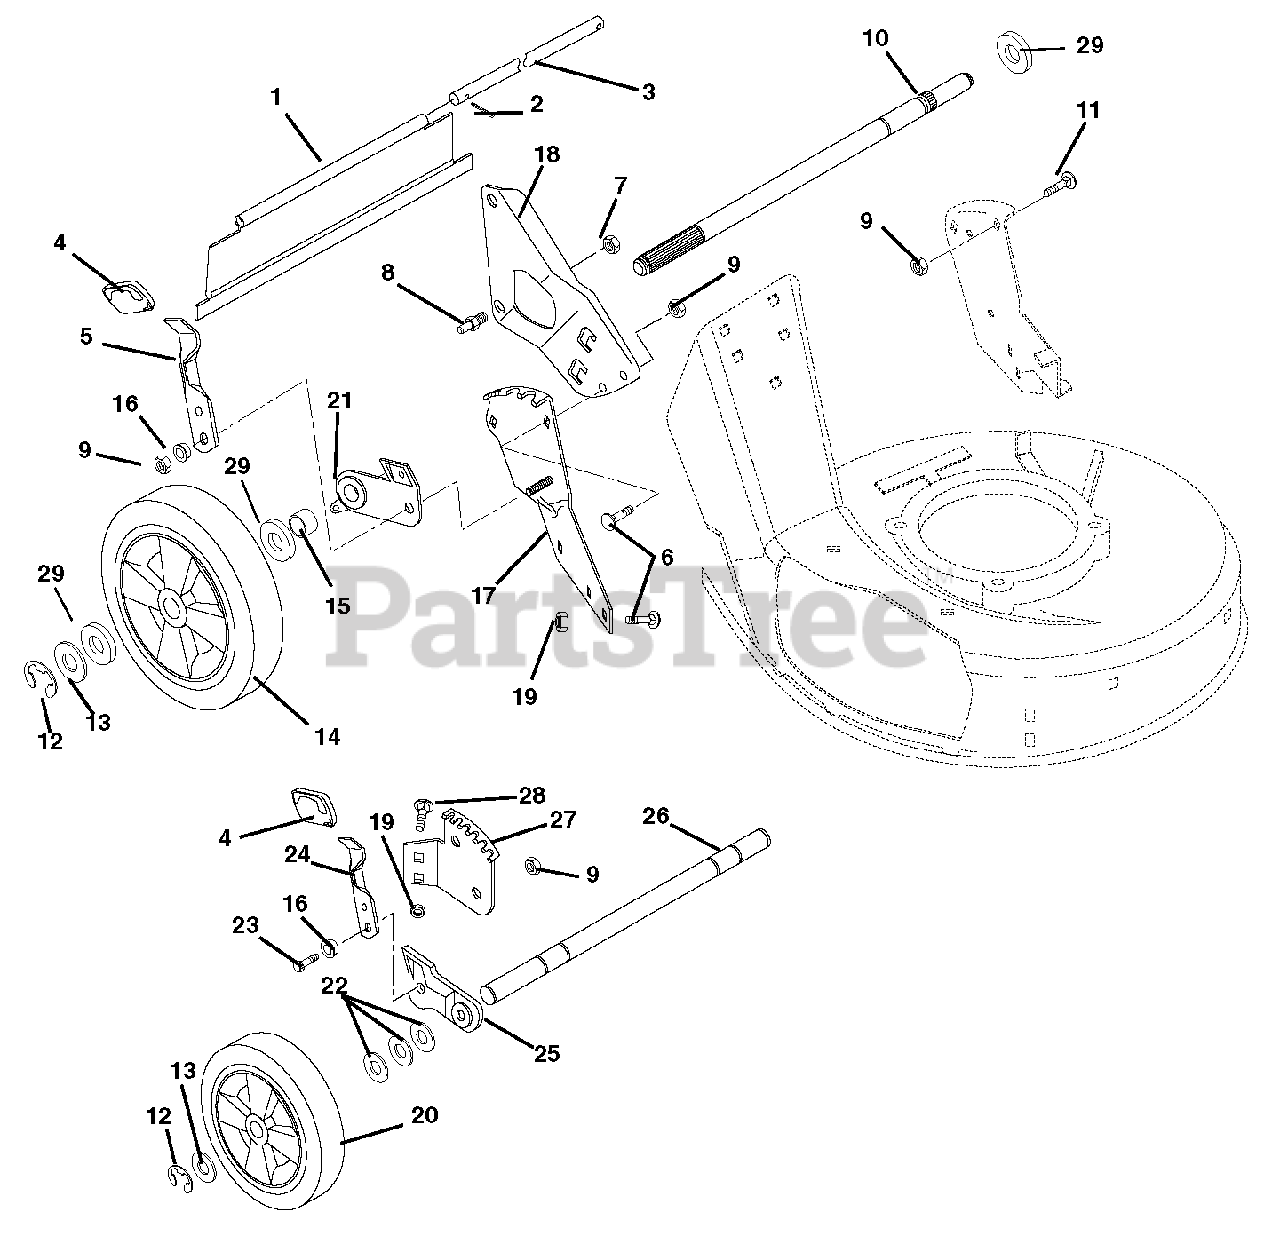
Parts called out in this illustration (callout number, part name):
1	Rear Protective Guard, Self Propelled
1	Rear Protective Guard, Push
2	Pin, Cotter .06 x .50
3	Rod
5	Lever, Height Adjustment
6	Bolt, Round Head Square Neck .31-18 x .62
7	Nut, Locking Center .38-16
8	Handlebar Stud
9	Nut, Locking-Top-Flange Center .31-18
10	Rear Axle
11	Bolt, Round Head Square Short Neck .31-18 x 1.00
12	Ring, Retaining External .50 x .042
13	Washer, Flat Steel .505 x .88 x .072
14	Wheel, Left Hand Rear
14	KIT - REAR WHEEL REPLACEMENT-PUSH
14	Wheel, 10.50"
14	Tire Skin 10 x 2.00
15	Spacer Tube
16	Bushing, Flange .312 x .50 x .344 x .88
17	Rear Quadrant-Left Hand
17	Rear Quadrant-Right Hand
18	Bracket, Handlebar Mounting-Right Hand
18	Bracket, Handlebar Mounting-Left Hand
19	Nut, Locking Top Flange .31-18
20	Wheel, Front
21	REAR BRACKET AND BEARING ASSY LH
21	REAR BRACKET AND BEARING ASSY RH
21	Rear Bracket and Bearing Assembly Left Hand
21	Rear Bracket and Bearing Assembly Right Hand
22	Washer, Flat Steel .520 x .827 x .062
23	Bolt, Hex .31-18 x 1.00 Grade 5
24	Lever, Front Height Adjustment
25	Left Hand Bracket Assembly
25	Right Hand Bracket Assembly
26	Front Axle
27	Front Quadrant, Left Hand
27	Front Quadrant, Right Hand
28	Bolt, Round Head Square Neck .31-18 x .50 Grade 5
29	Spacer .531 x 1.00 x .195
